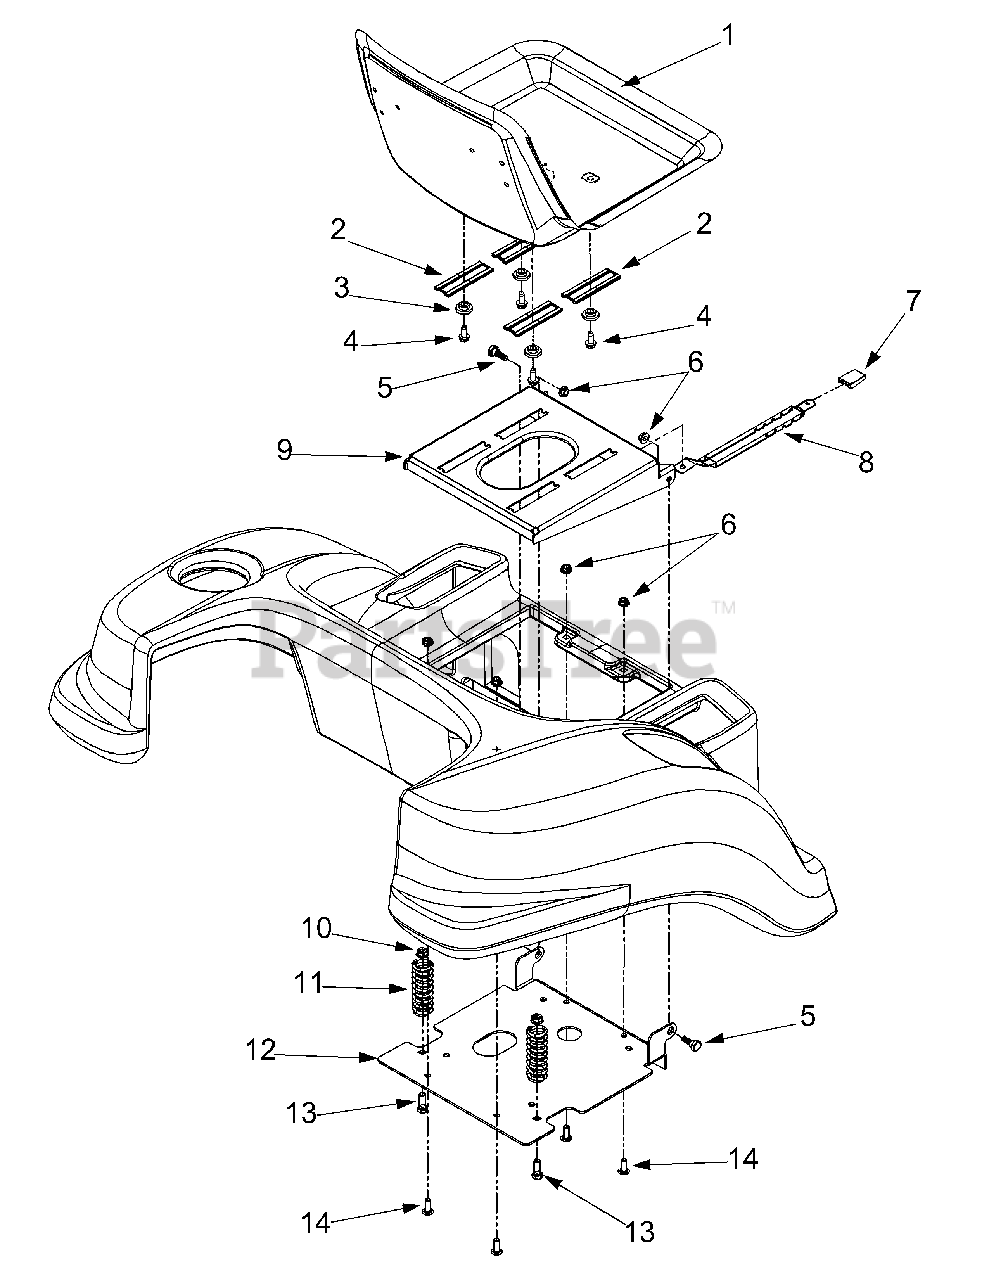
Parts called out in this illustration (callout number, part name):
3	Shoulder Spacer
4	Hex Washer Screw 5/16-18 x .75
5	Shoulder Screw
6	Flange Lock Nut 5/16-18
7	Height Knob
8	Spring Index
11	Compression Spring
12	Seat Plate
13	Hex Cap Screw 3/8-16 x 1.0
14	Bolt 5/16-18 x .875
